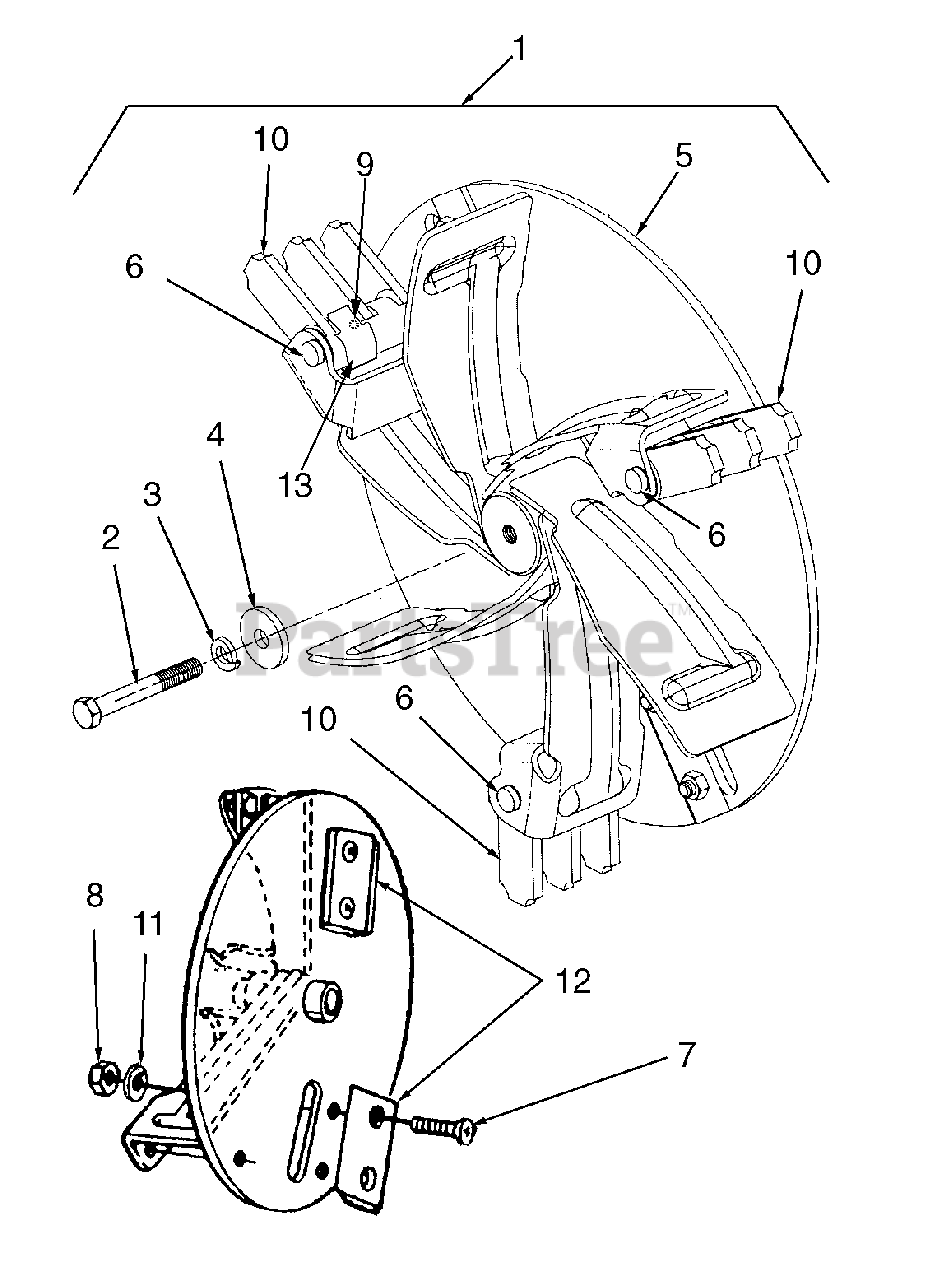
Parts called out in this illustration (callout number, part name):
1	Impeller Ass'y, Complete
2	Screw, Hex Cap, 3/8-24 x 2.75 GR5
3	Washer, Lock, 3/8 Heavy Duty 1
4	Washer, Flat, .406 x 1-1/4 HD1
5	Impeller Assembly
6	Pin, Clevis
7	Screw, Flat Hd. Cap, 5/16-24 x 1.0
8	Nut, Hex Insert Lock, 5/16-24
9	Pin, Spirol, 5/32 x 1.125
10	Blade, Flail
11	Washer, Lock, 5/16
12	Blade, Chipper
13	Pin Retaining Clip
